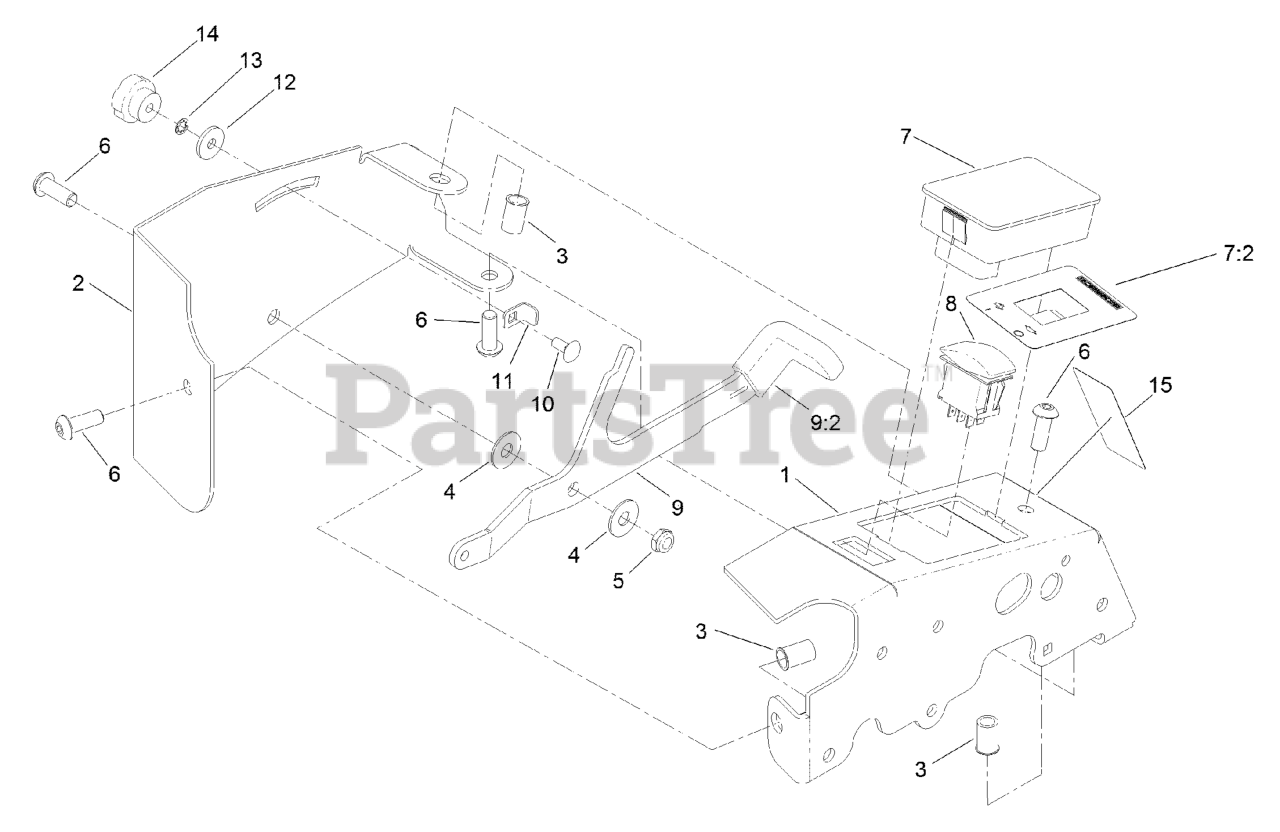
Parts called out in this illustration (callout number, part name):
1	BRACKET-MOUNT
2	COVER-CONTROLLER, SPREADE
3	NUT-CLINCH
6	SCREW-HSBH
7	Spreader Control Module ASM
7:2	DECAL-SPEED, IMPELLER
10	SCREW-CARR
11	BRACKET-GATE, SET
12	WASHER-FRICTION
13	WASHER-LOCK, INT
14	KNOB-CHUTE
15	DECAL-CONTROL, SPREAD
